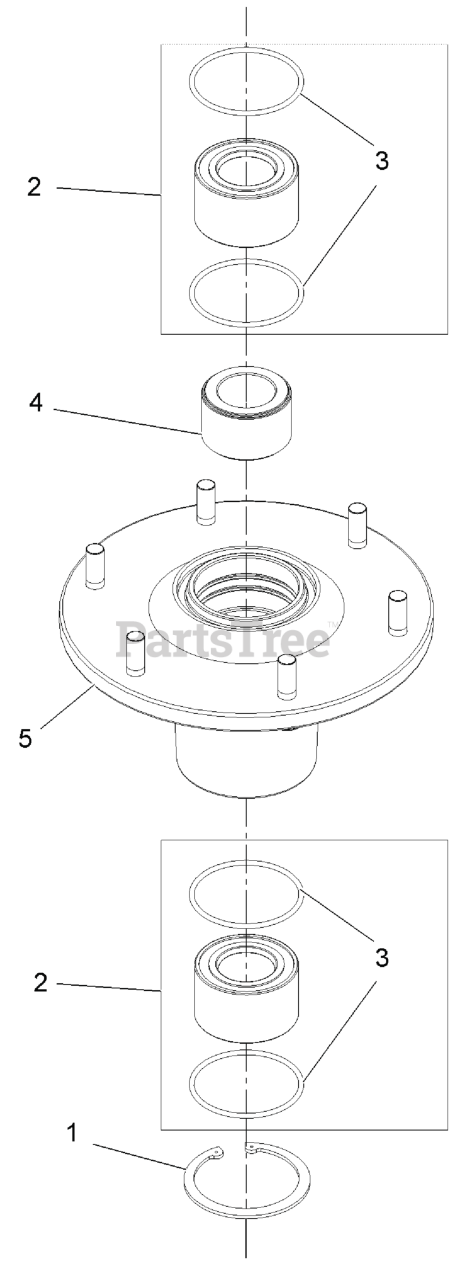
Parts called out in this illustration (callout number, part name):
1	RING-RETAINING
2	ASM, BEARING W/ORINGS
4	SPACER,BEARING
5	ASM,HOUSING W/STUDS
